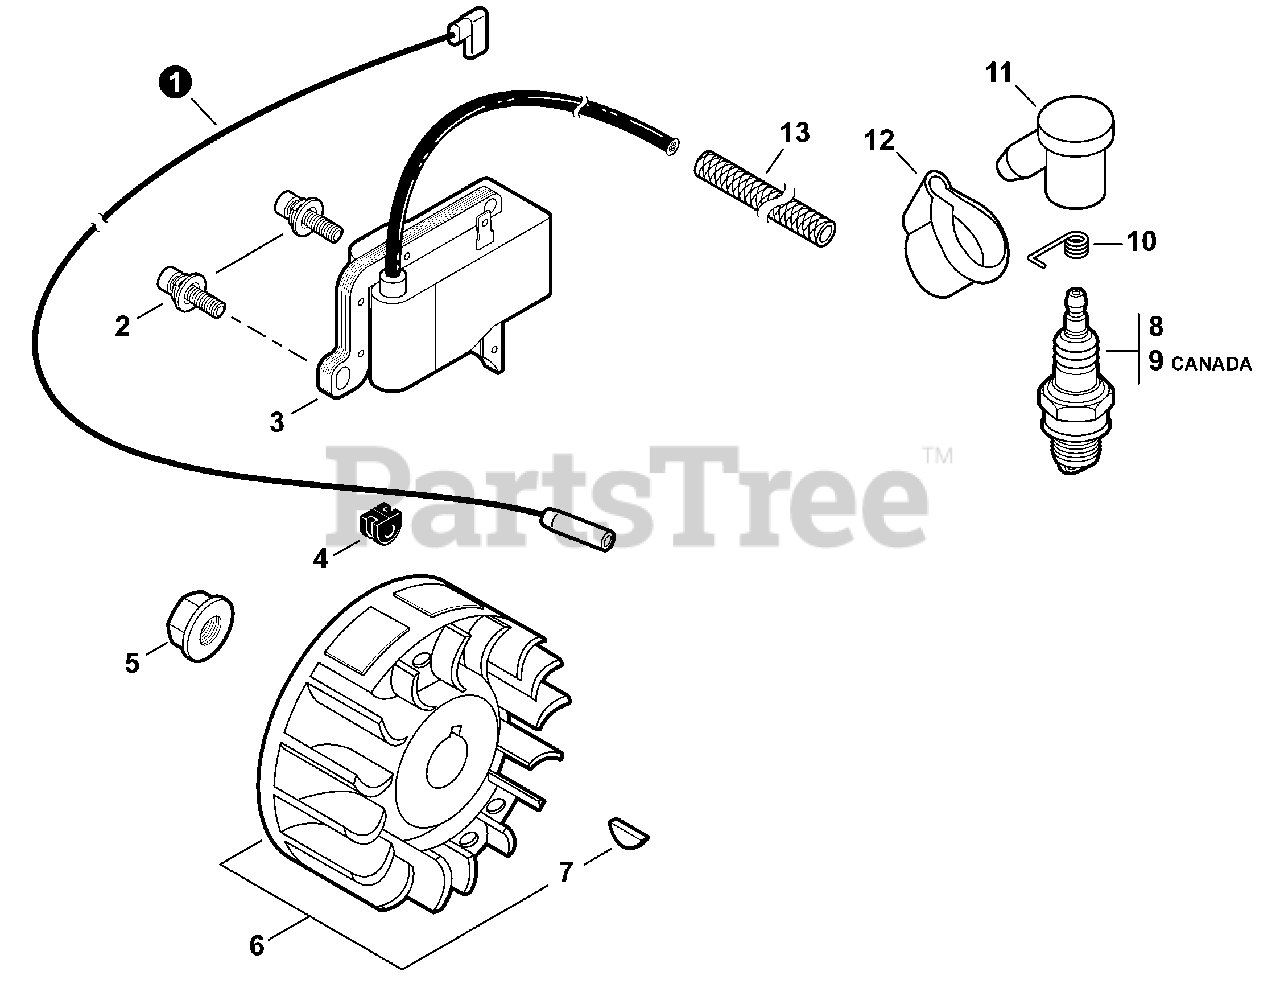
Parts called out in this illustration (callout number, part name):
1	LEAD 170 MM
2	BOLT 5×20
3	COIL, IGNITION
5	NUT, FLANGE 10×1.25
6	FLYWHEEL KIT
7	KEY, WOODRUFF 3×14
8	SPARK PLUG - BPM7A
9	SPARK PLUG - BPMR7A
10	TERMINAL, SPARK PLUG
11	CAP, SPARK PLUG
12	COVER, DUST
13	TUBE, INSULATOR 7×8.6×55
